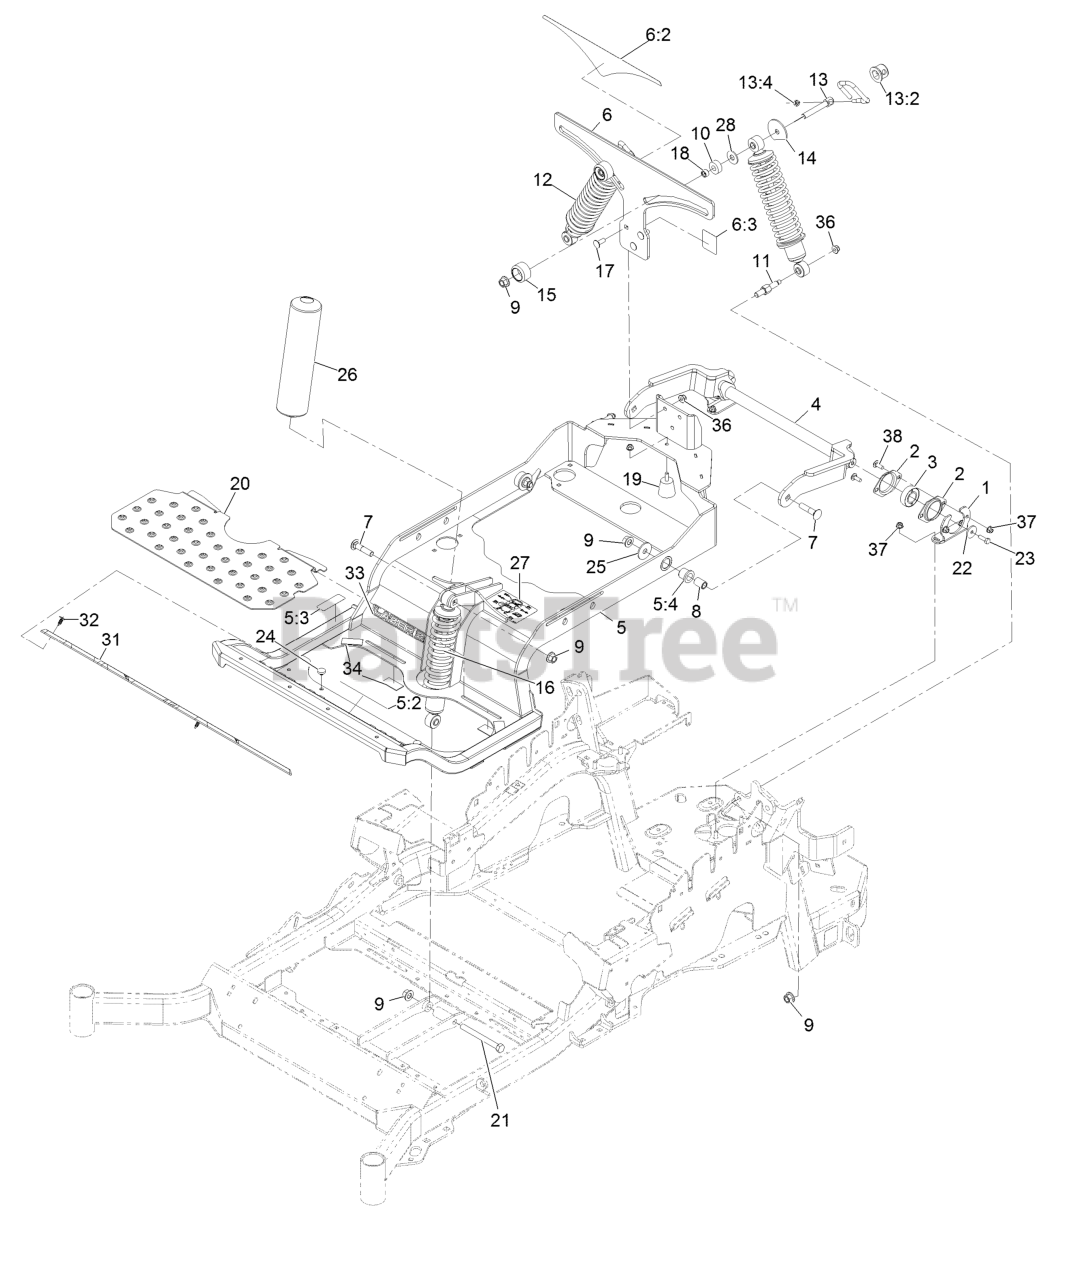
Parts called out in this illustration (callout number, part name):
1	Bracket-Bearing
2	Housing-Bearing, Flange
3	Bearing
4	Arm-Trailing
5	Subframe ASM
5:2	Decal-Danger
5:3	Decal-Brake, Parking
5:4	Bushing-Flange
6	Bracket-Mounting
6:2	Decal-Adjustment, Ride
6:3	Decal-Lock, Cam
7	Bolt-Carriage 1/2-13 X 2 1/4
8	Spacer-Aluminum
9	Nut-Lock 1/2-13
11	Bolt-Shoulder
12	Shock/Spring ASM
13	Cam Lock ASM
13:2	Cap-Lock
13:4	Nut-Hex Nyloc 5/16-18
14	Plate-Stop
15	Knob-Front
16	Shock/Spring ASM
17	Bolt-Carriage 3/8-16 X 1
18	Bearing-Needle
19	Bumper-Rubber
21	Screw-HH 1/2-13 X 5
22	Washer-Flat
23	Screw-HH 5/16-18 X 1 W/Patch
26	Cover-Shock
27	Decal-Service Aid
28	Washer
31	Floor Mat
32	Plug-Plastic
33	Decal-Lazer Logo
34	Pad-Rubber
36	Nut-Nyloc 3/8-16 Flg
37	Nut-Nyloc 5/16-18 Flg
38	Bolt-Carriage 5/16-18 X 7/8
